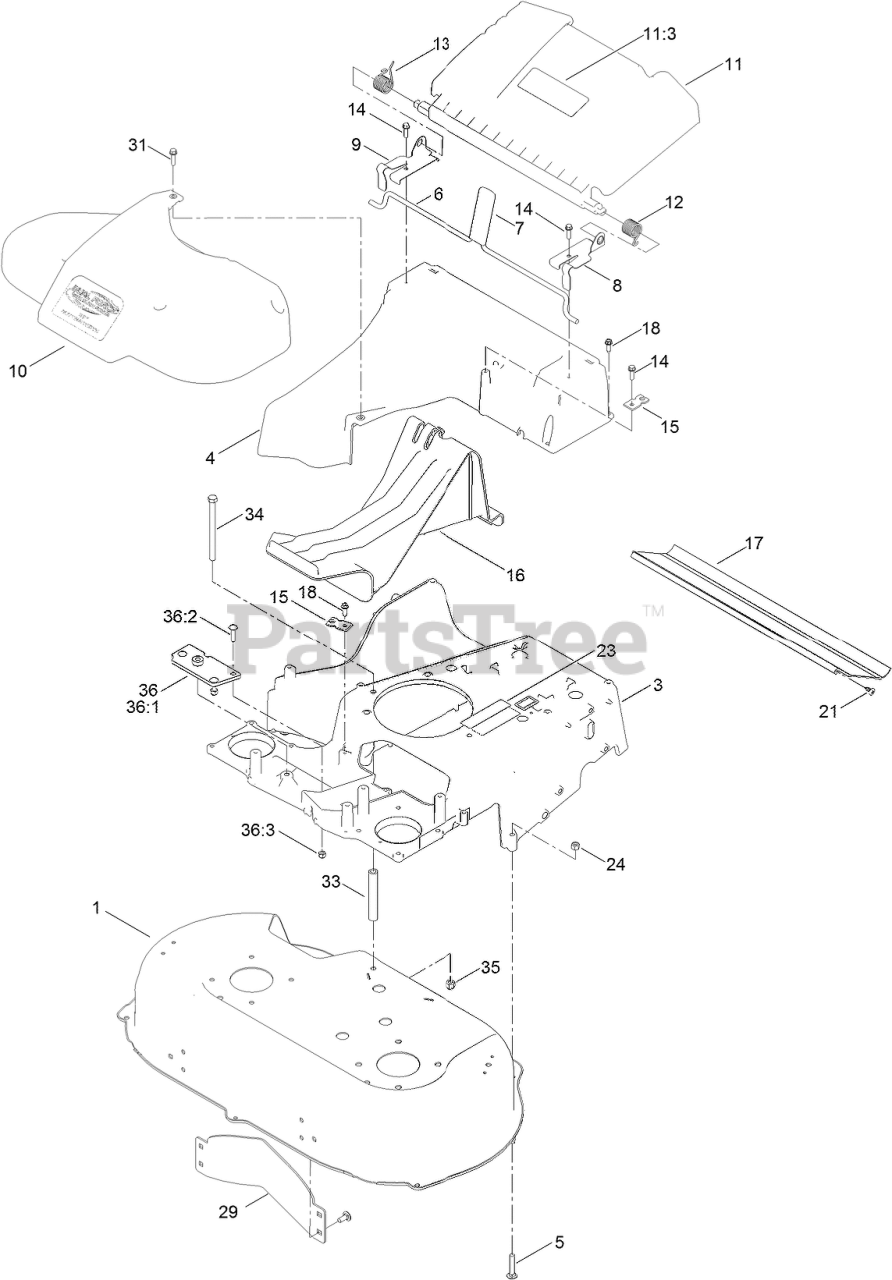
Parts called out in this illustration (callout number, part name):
1	HOUSING ASM
3	FRAME
5	BOLT-CAR
6	ROD-RELEASE, HANDLE
7	GRIP-LEVER
8	BRACKET-DOOR, LH
9	BRACKET-DOOR, RH
10	BELT COVER ASM
11	REAR DEFLECTOR ASM
11:3	DECAL-WARNING
12	SPRING-TORSION
13	SPRING-TORSION
14	SCREW-HWH
15	BRACKET-CABLE, TRACTION
16	PLUG-MULCH
17	SHIELD-TRAILING
18	SCREW-HWHTF
21	SCREW-PTH
23	DECAL-ARRESTOR, SPARK
24	NUT-LOCK, NI
29	BAFFLE-CONTROL
31	SCREW-HWHTF
33	SPACER-SHIELD
34	SCREW-HH
35	NUT-HEX
36	FRAME PLATE KIT
36:1	PLATE-FRAME
36:2	SCREW-CARR
36:3	NUT-LOCK, NI
